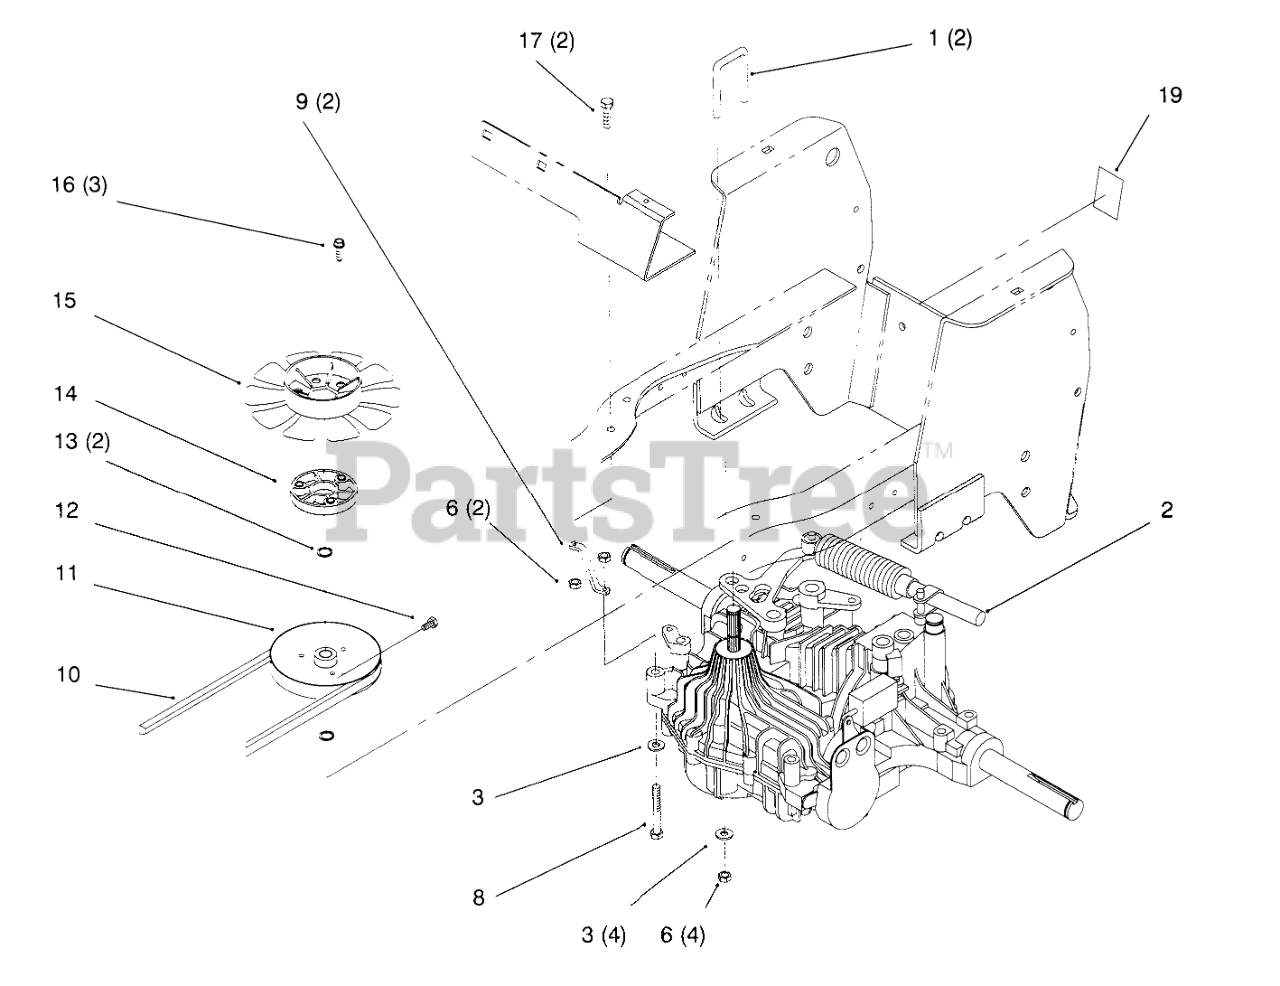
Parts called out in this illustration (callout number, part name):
1	U-BOLT
2	Transaxle-Tuff Torq K61
3	WASHER-PLAIN
6	NUT-LOCK, NI
8	SCREW-HH
9	Strap-Torque
10	Belt-Hydro
11	PULLEY-HYDRO TRANS
12	SCREW-HSH
13	SNAP RING
14	SPACER - FAN
15	FAN - HYDRO
16	SCREW-HWHTF
17	SCREW-HH
19	DECAL-VALVE, HYDRO
